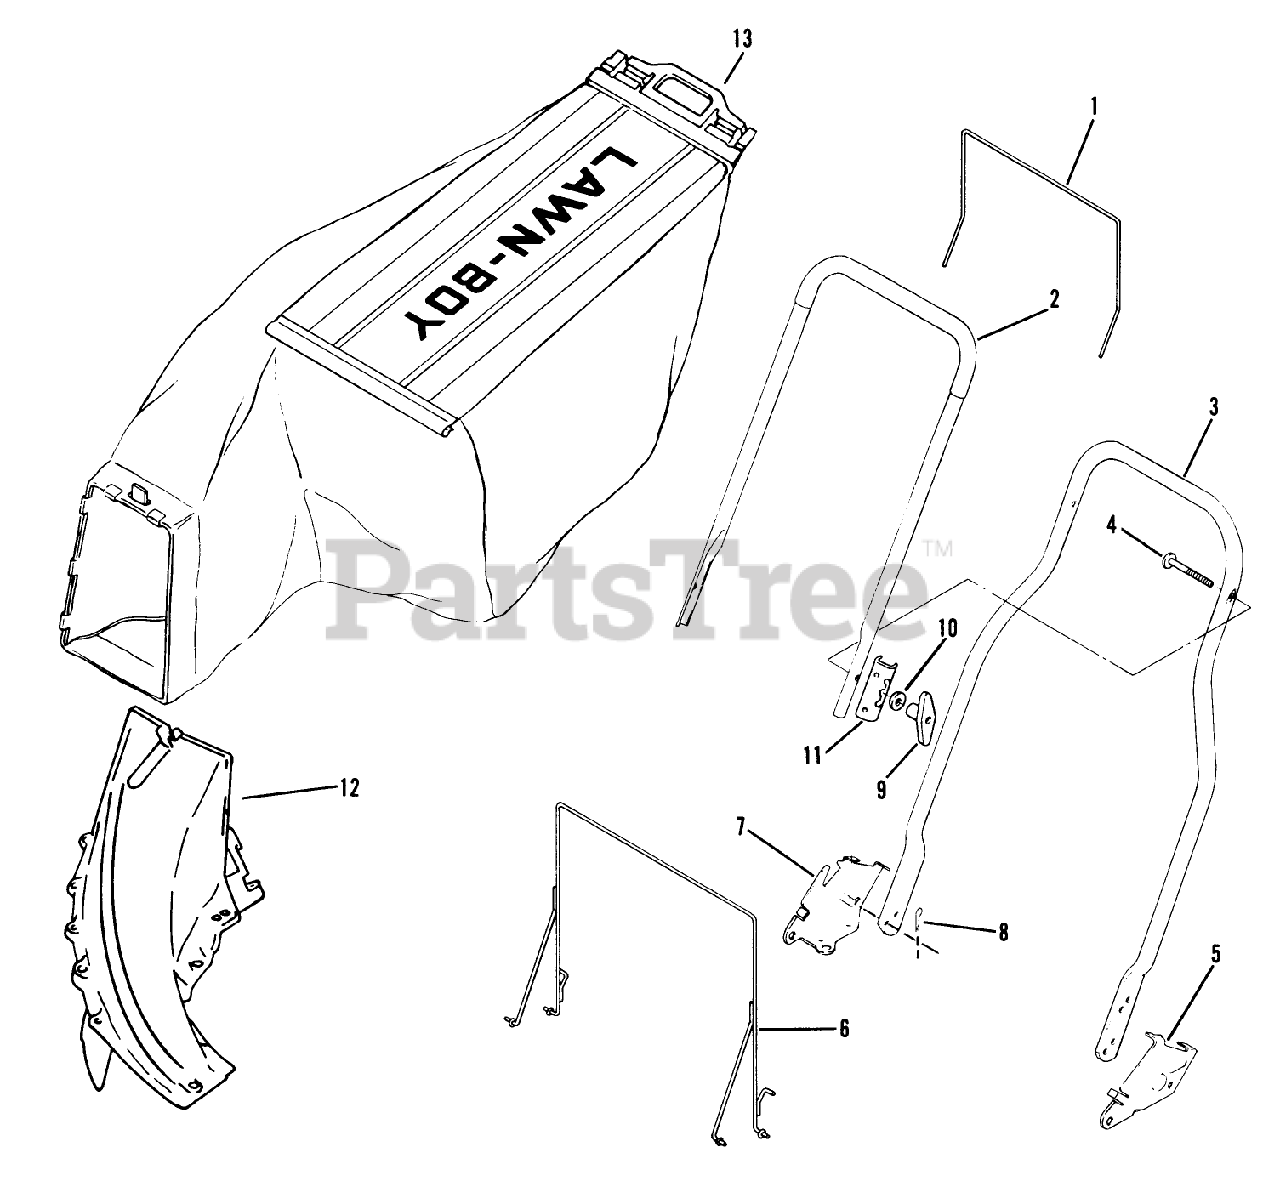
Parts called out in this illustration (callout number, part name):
1	HANGER
8	HAIR PIN
9	NUT-WING
10	WASHER-CURVED
11	BRACKET R/B 613462
